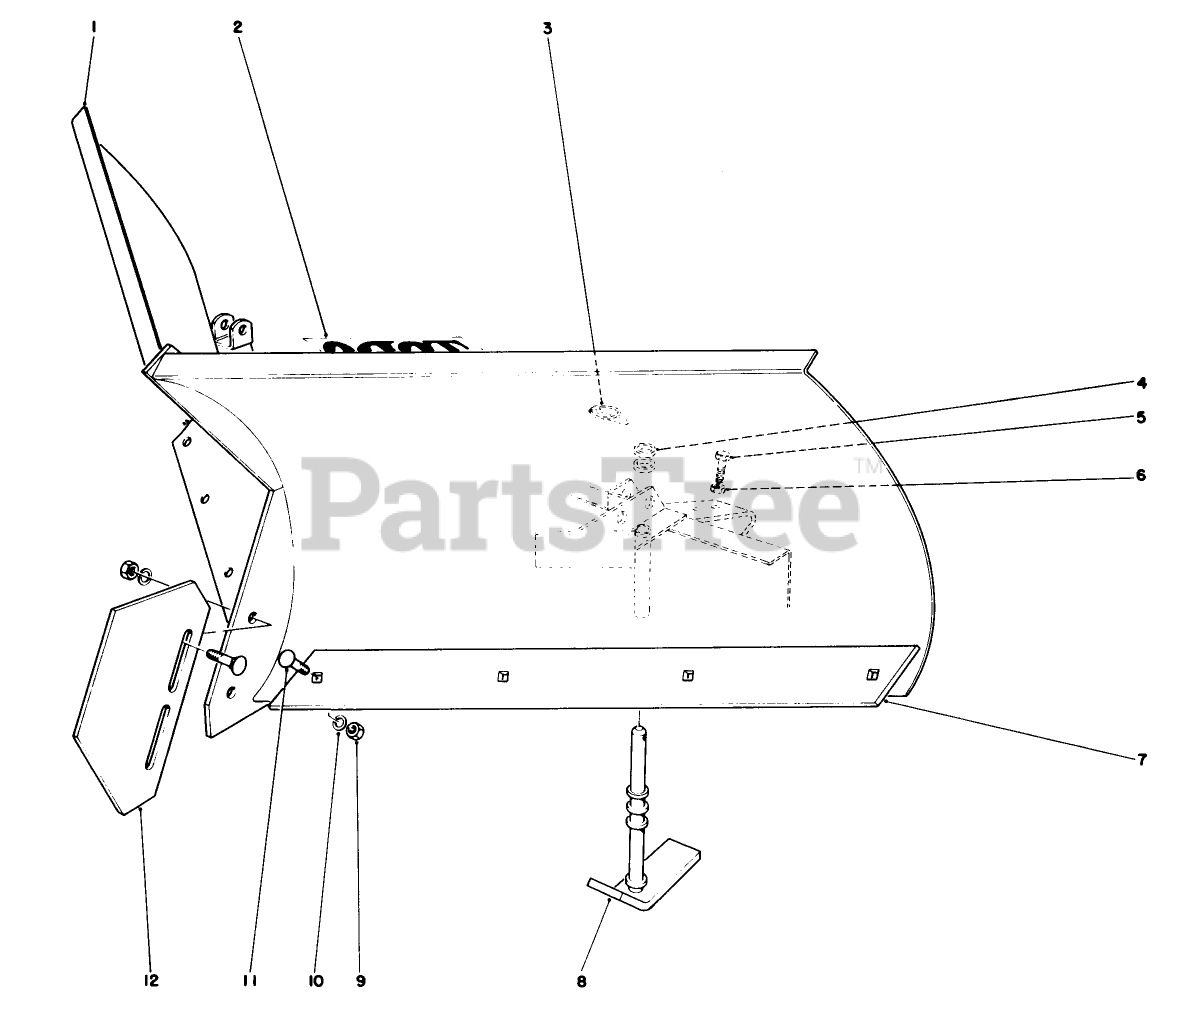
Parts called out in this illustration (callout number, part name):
1	V-Plow
2	DECAL
3	PIN-LYNCH
4	SPACER TUBE B
5	SCREW-HH
6	NUT-JAM
7	Blade-Scraper
8	Skid
9	NUT-HH
10	WASHER-LOCK
11	SCREW-CARR
12	Nose Skid
